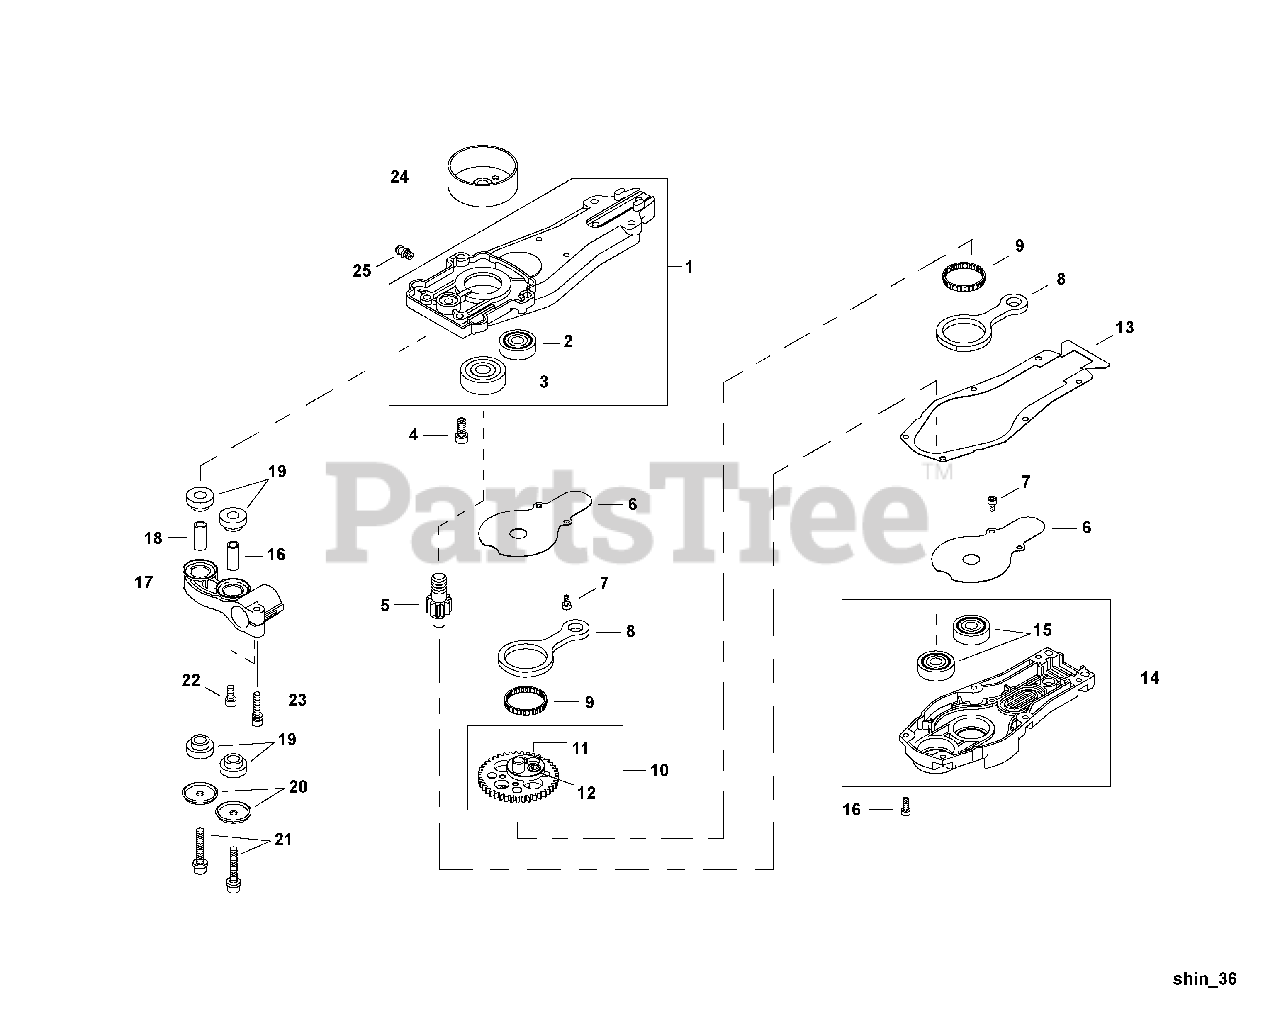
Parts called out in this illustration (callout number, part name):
1	GEAR CASE HOUSING ASSY
2	BEARING, BALL 6200ZZ
3	BEARING, BALL 6301 DDU
4	BOLT 6×16
6	PLATE, GEAR CASE
7	BOLT 4×8
9	BEARING, NEEDLE 30
10	CAM GEAR ASSY
11	BOLT M5×6
13	GASKET, GEAR CASE
14	COVER ASSY, GEAR CASE
15	BEARING, BALL 6200ZZ
16	BOLT 4×14
17	MOUNT, HANDLE
18	COLLAR 6
19	CUSHION
20	WASHER 6
21	BOLT M6×35
22	BOLT 5×12
23	BOLT M5×25
24	DRUM, CLUTCH
25	FITTING, GREASE
